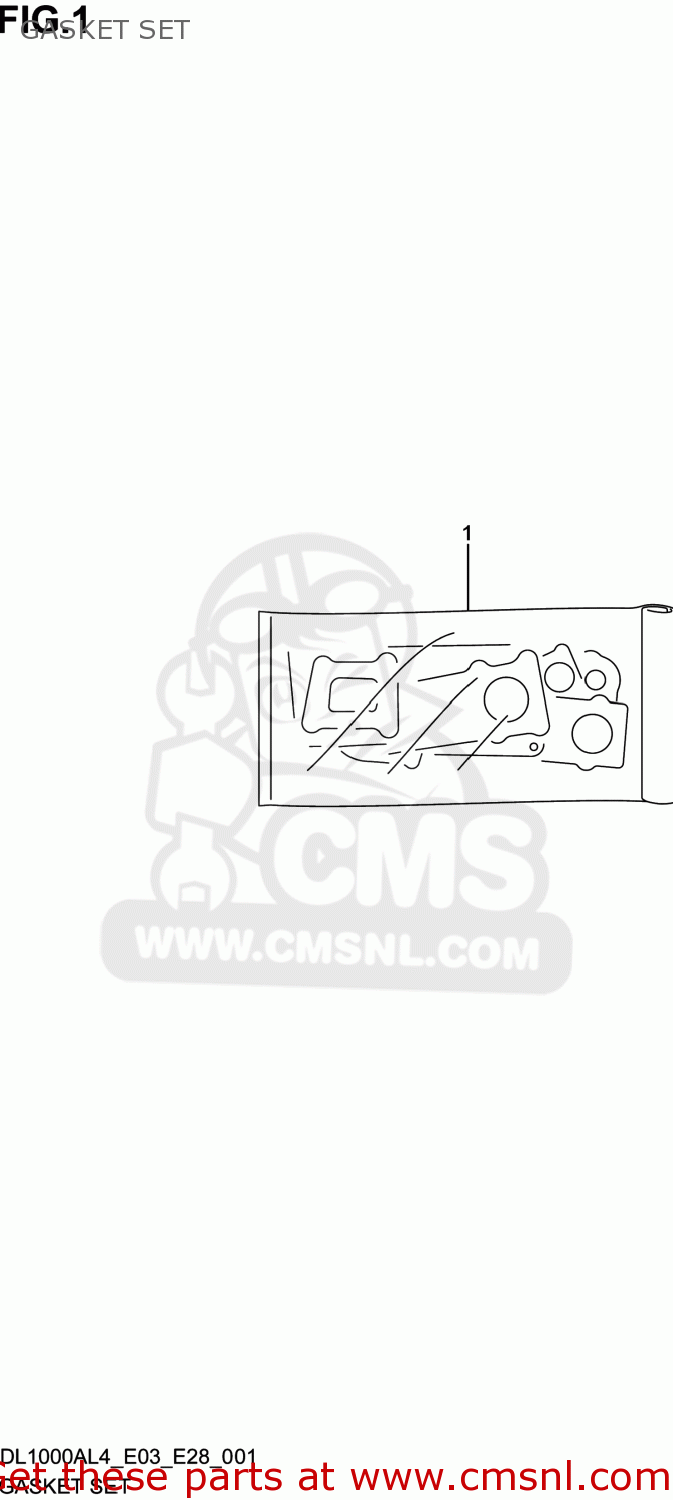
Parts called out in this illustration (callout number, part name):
1	GASKET SET (NAS)
2	GASKET,CYLINDER HEAD (NAS)
3	GASKET,CYL HEAD COVER NO.1 (NAS)
4	GASKET,CYL HEAD COVER NO.2
5	GASKET,CYLINDER FRONT (NAS)
6	GASKET,CYLINDER REAR (NAS)
7	GASKET,CLUTCH COVER (NAS)
8	GASKET,MAGNETO COVER (NAS)
9	GASKET,GEAR SHIFT COVER (NAS)
10	GASKET,TENSIONER ADJUSTER (NAS)
11	GASKET,TENSIONER ADJUSTER (NAS)
12	GASKET,EXHAUST PIPE (NAS)
13	CONNECTOR,JT
14	O RING,FUEL PUMP
15	GASKET(13.8X18.8X4.8) (NAS)
16	O RING(D:3.1,ID:32.7)
17	O RING(D:2.4,ID:55.6)
18	O RING,WATER PUMP CASE
